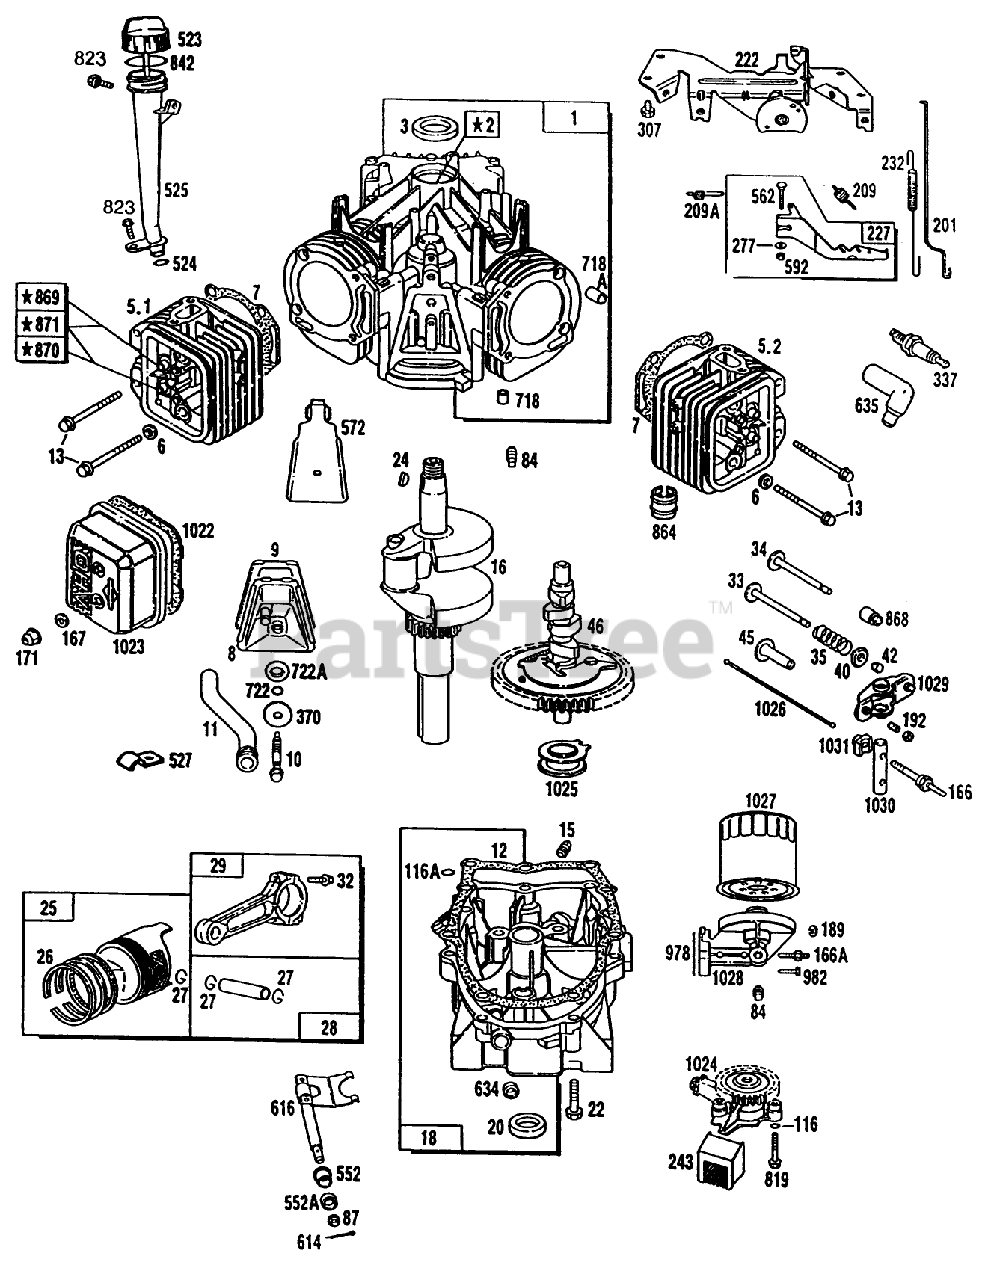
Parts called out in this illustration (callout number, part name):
1	BRIGGS-807511
2	BRIGGS-807687
3	BRIGGS-805101
5.1	BRIGGS-807508
5.2	BRIGGS-807510
6	BRIGGS-805193
7	BRIGGS-805111
9	BRIGGS-805379
10	BRIGGS-805194
11	BRIGGS-805362
12	BRIGGS-805112
13	BRIGGS-805097
18	BRIGGS-807638
20	BRIGGS 805049
22	BRIGGS-805017
24	BRIGGS-805016
26	BRIGGS-870620
27	BRIGGS 805099
28	BRIGGS-807621
29	BRIGGS-807622
32	BRIGGS-805395
33	BRIGGS-807681
34	BRIGGS-807680
35	BRIGGS 805078
40	BRIGGS-805092
42	BRIGGS-807683
45	BRIGGS 805354
46	BRIGGS-807542
84	BRIGGS-805059
87	BRIGGS-805054
116	BRIGGS-805058
116A	BRIGGS-805198
166A	BRIGGS 805073
167	BRIGGS-805420
171	BRIGGS 805019
189	BRIGGS-805449
192	BRIGGS-807623
201	BRIGGS 805480
209	BRIGGS-805462
209A	BRIGGS-805453
222	BRIGGS-807610
227	BRIGGS-807528
243	BRIGGS-805312
277	BRIGGS-805018
307	Screw
337	Spark Plug
370	Washer
523	BRIGGS-807516
524	BRIGGS 805011
527	BRIGGS 223167
552	BRIGGS-805412
552A	Bushing
572	Baffle
592	BRIGGS 805383
614	BRIGGS 805417
615	Choke Shaft Retainer
634	Washer
635	Elbow
718	Dowel Pin
718A	BRIGGS 805102
819	Screw
823	Screw
842	BRIGGS-805012
864	BRIGGS 805083
868	BRIGGS-805094
869	BRIGGS-805085
870	BRIGGS-805086
871	BRIGGS-805084
978	BRIGGS 805250
982	BRIGGS-805030
1022	BRIGGS-805028
1023	BRIGGS-805100
1024	BRIGGS-807546
1025	BRIGGS-805313
1026	OBTAIN LOCALLY
1028	BRIGGS 805292
1029	BRIGGS-807557
1030	BRIGGS-805342
